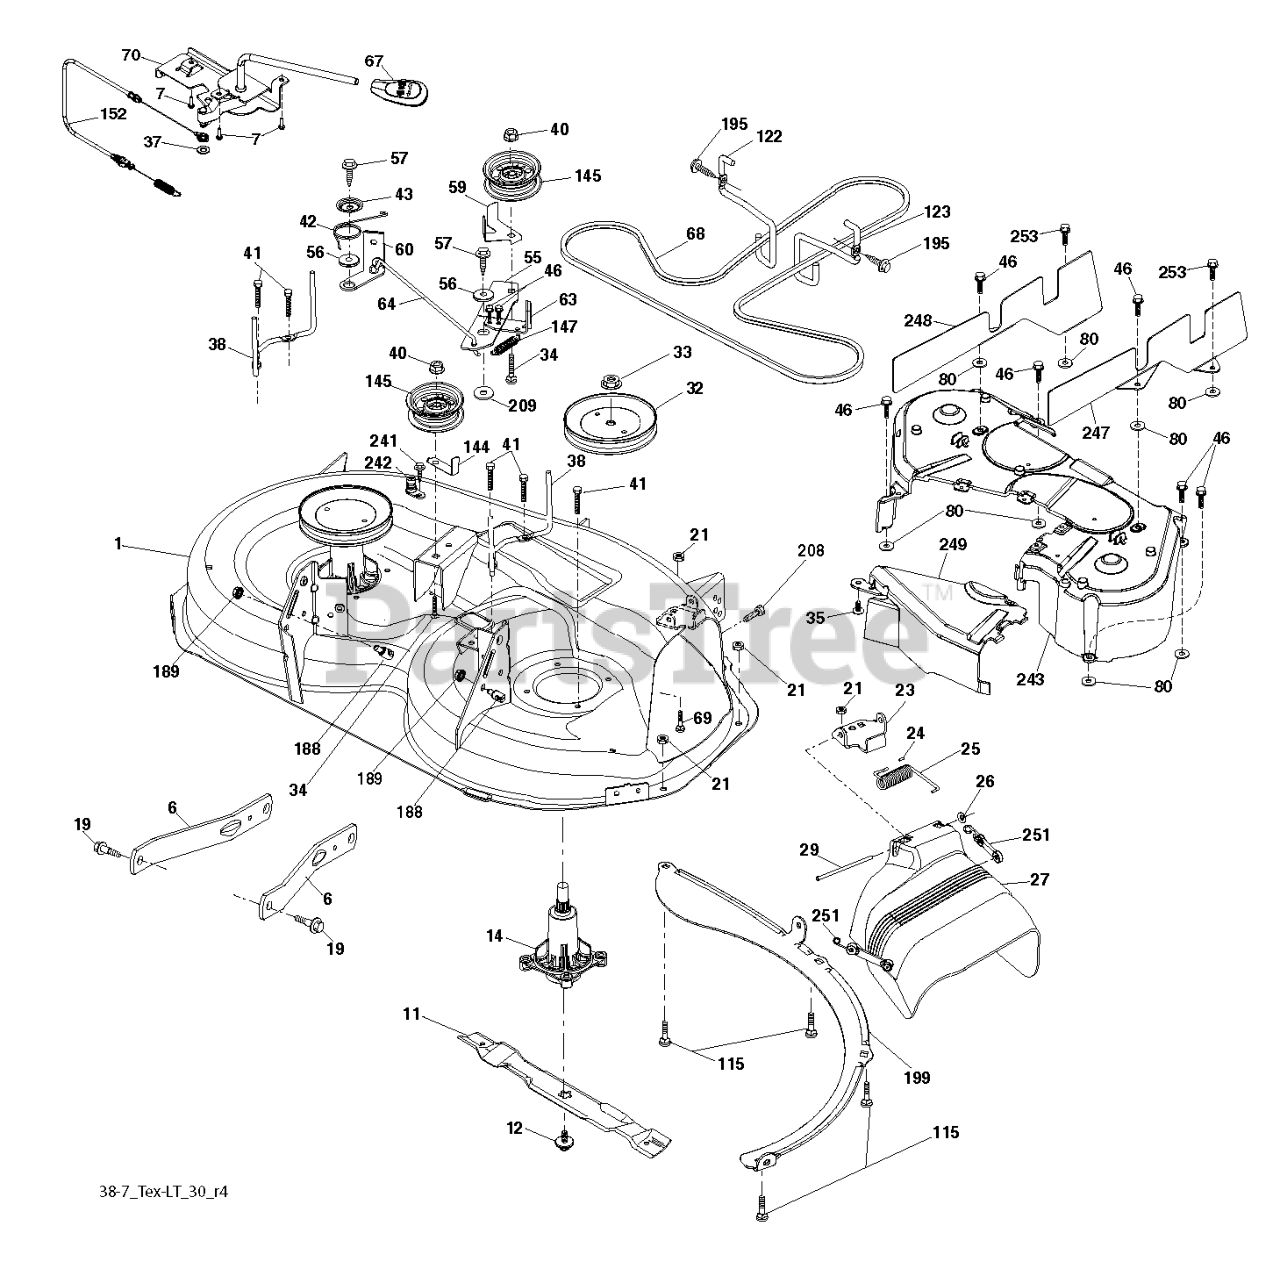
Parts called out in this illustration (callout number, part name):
1	DECK.38.WELDMENT.GREY
6	ARM.SUSPENSION.MOWER.R
7	SCREW.#10 X 0.750.BOS
11	BLADE.2 IN 1.38"DECK
12	SCREW.SEMS.7/16-20X1.HEX.HEAD
13	SHAFT ASM.MNDRL.N/GREASEABLE
14	RP.HOUSING.MANDREL.4PT.
15	BEARING.MANDREL.TOP.EXTENDED
19	BOLT.SHOULDER
21	LOCKNUT
23	BRKT.DEFLECTOR.38"2005+
24	CAP-SLEEVE LT
25	SPRING.TORSION.DEFLECT
26	NUT PUSH M
27	SHIELD ASM.DFLCTR MWR.38-7"BLK
29	ROD.HINGE
32	PULLEY.MANDREL.5.0.PD.38"
33	NUT.FLANGE.LOCK.TOP
34	BOLT.3/8-16X1.50
35	FASTENER.XMAS.TREE
37	WASHER
38	KEEPER BELT LH MANDREL
40	NUT LOCK FLG 3/8-16 UNC
41	BOLT.HEX.WASHR.HED.313-18X1.19
42	SPRING.TORSION.BRAKE
43	SRPING.TORSION.RETAINE
46	SCREW.1/4-20X5/8
55	IDLER.ARM
56	SPACER.RETAINER
57	SCREW 3/8-16X1
59	GUARD, BELT
60	ARM BRAKE MOWER RH 38"
63	RP ARM.BRAKE.MOWER.38"LH.TEX
64	LINK BRAKE
67	HANDLE.CLUTCH.CABLE.LT
69	BOLT
70	CLUTCH.ASM.MANUAL.LT.PRED
80	PALNUT 1/4
115	BOLT.CARR.5/16-18X5/8.SHORT
122	KEEPER BELT ENGINE LH
123	KEEPER BELT RH
144	KEEPER BELT
145	PULLEY.IDLER.48"PRIMARY
147	SPRING RETURN
152	CABLE.CLUTCH.MANUAL.
188	STUD.FASTNER.W/ANTI-ROTATE
189	NUT LOCK HEX FLANGE 5/16-18
195	SCREW, 3/8-16X3/4
199	BAFFLE.VORTEX.FRONT.38"
206	Washer 9/32 x 7/8 x 16 Ga.
209	WASHER 12/32X2X10GA
241	SCREW.TT.#10-32X.5.3/8.FLANGE
242	PORT.WASHOUT
243	COVER DECK 38-7
247	SHIELD DECK RIGHT
248	SHIELD DECK LEFT
249	COVER CABLE CLUTCH
251	ELASTIC STRAP KIT
253	SCREW
